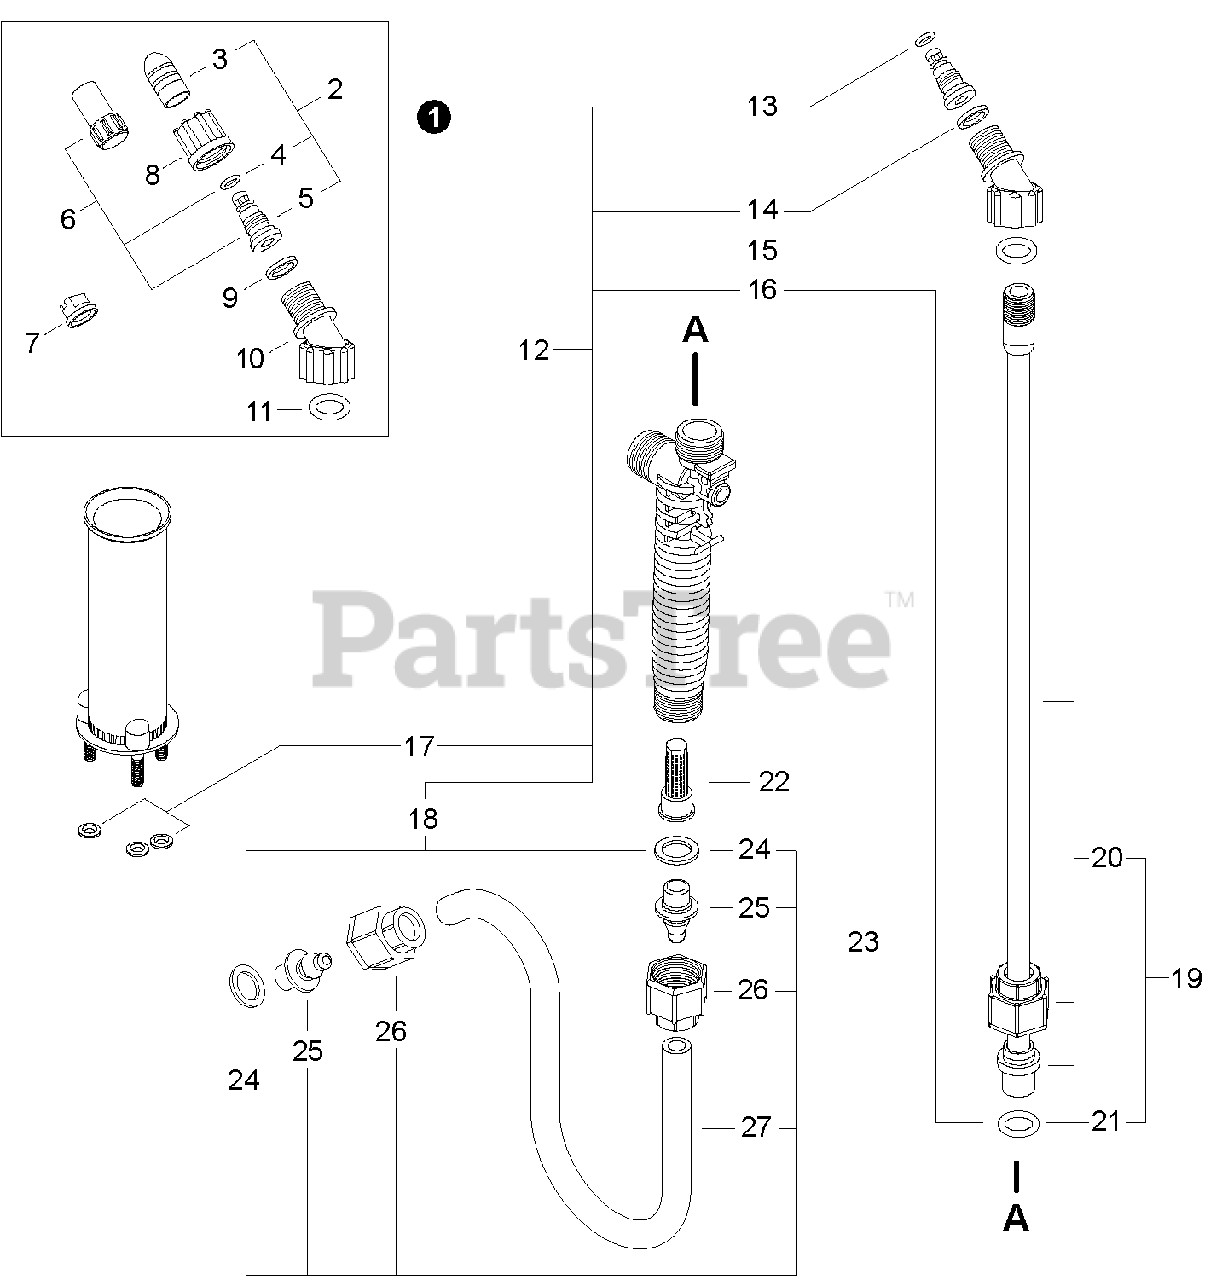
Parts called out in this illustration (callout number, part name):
1	NOZZLE KIT
2	NOZZLE KIT - BRASS
3	CAP, NOZZLE - BRASS
4	O-RING, NOZZLE
5	BODY, NOZZLE
6	NOZZLE KIT - PLASTIC
7	NOZZLE - FLAT FAN
8	NUT, NOZZLE
9	GASKET, NOZZLE
10	ELBOW, NOZZLE
11	O-RING, ELBOW
12	GASKET KIT, BPE
13	O-RING, NOZZLE
14	GASKET, NOZZLE
15	O-RING, ELBOW
16	O-RING - 15X3
17	GASKET, STUD
18	GASKET, ADAPTER
19	SPRAY WAND ASSY
20	WAND, SPRAYER
21	O-RING - 15X3
22	FILTER, SPRAY GUN
23	HOSE ASSY
24	GASKET, ADAPTER
25	ADAPTER, HOSE - BLACK
26	NUT, HOSE
27	HOSE - 1210mm -- BLACK
